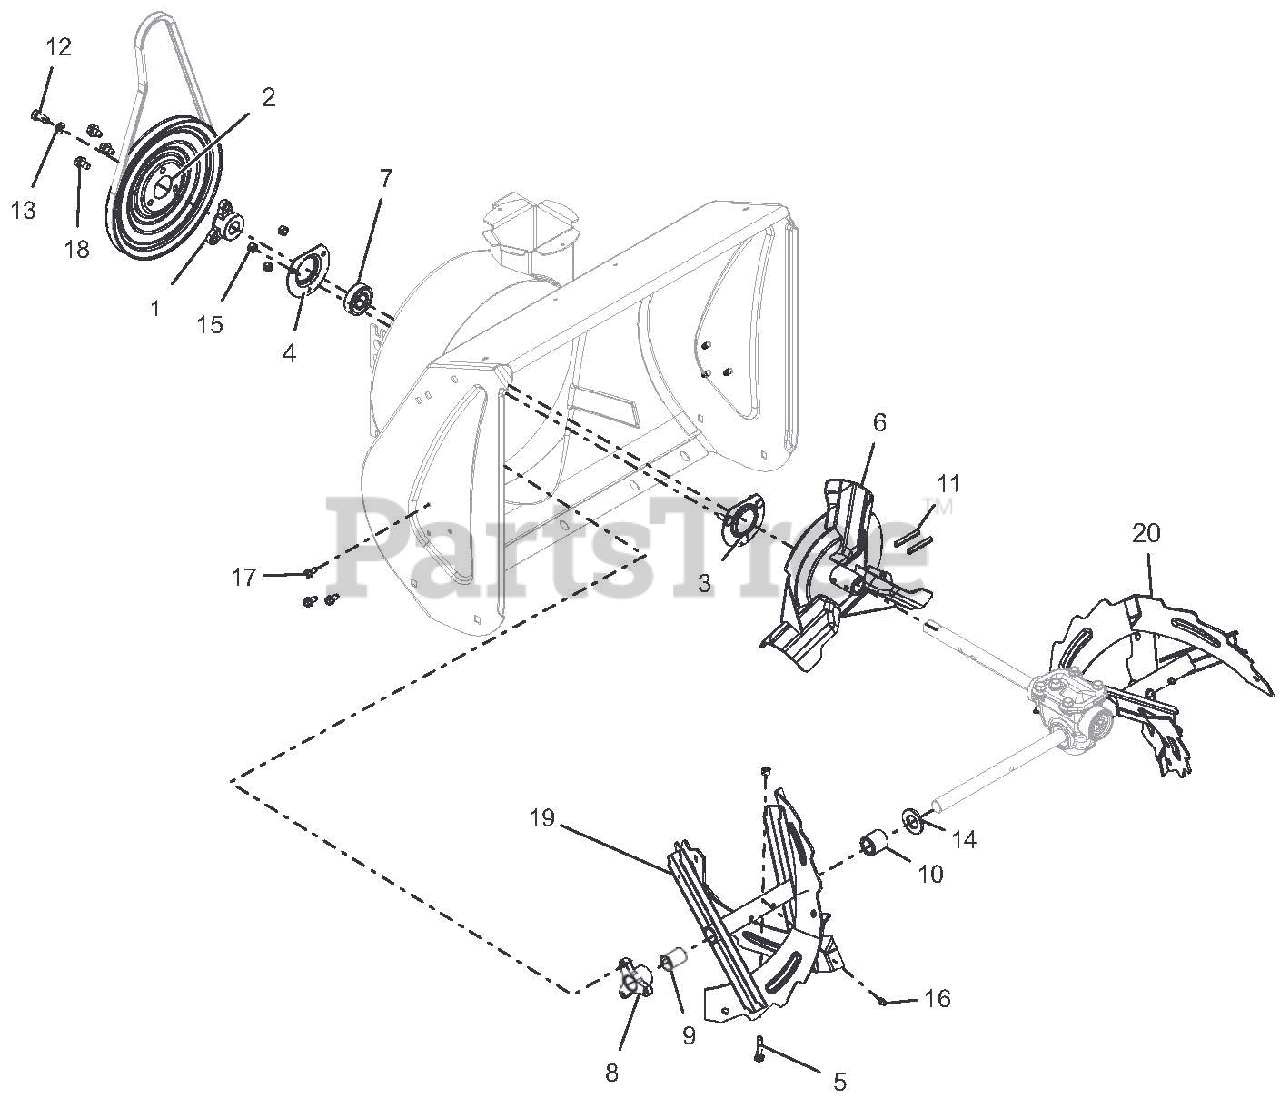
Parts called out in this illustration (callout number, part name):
1	PULLEY HUB, BOLT-ON D-BORE .75
2	PULLEY,SPIN FORM SINGLE GROOVE
3	BEARING FLANGE
4	BEARING FLANGE
5	SHEAR BOLT
6	IMPELLER, COMPACT 12" 3-BLADE
7	BRG-BALL .750X1.750X.50
8	BUSHING, RAKE SHAFT .75"
9	BSHG-FLG SPLIT NYLINER .75"ID
10	BSHG-SLV .75X1.12X1.062 NYL BK
11	PIN-ROLL .250X1.75
12	BLT-HEX .31-24X.75 YWZC GR5
13	WSHR-LK .312X.097 HVY YWZC
14	@WSHR-FL-STL.812X1.50X.135YWZC
15	@NUT-LK-CTR .25-20 YWZC
16	ZERK,FITTING .25X.125 DRIVE IN
17	SCR-TAP .25-20X.50 HWH TR YWZ
18	@SCR-TAP .31-18X.50 HWH TR YWZ
19	AUGER, 20" RH, BLK SERR W/ZERK
20	AUGER, LH 20", BLK SERR W/ZERK
